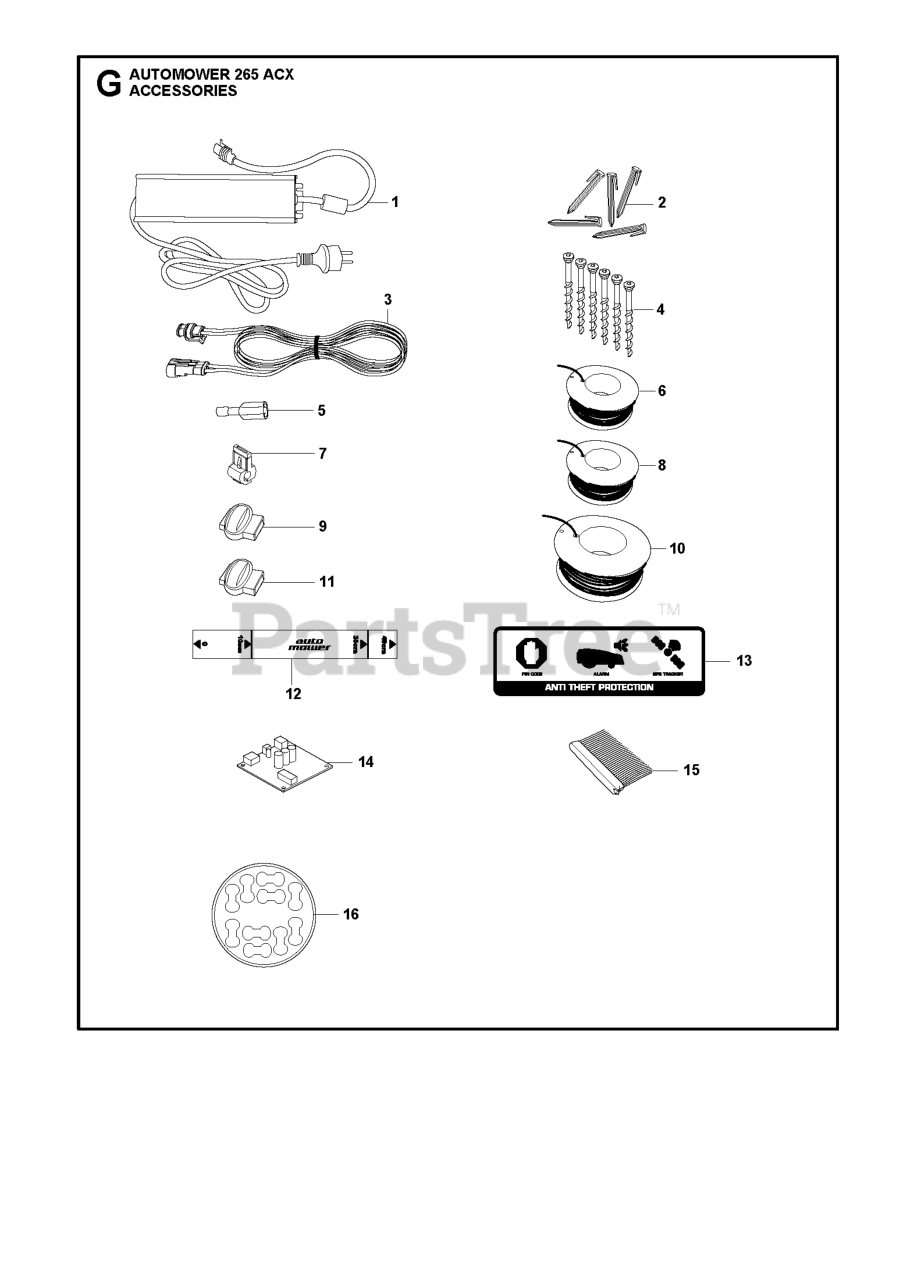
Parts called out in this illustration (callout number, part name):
2	STAPLE 100 PCS, BLISTER
4	SCREW 3 PCS, BLISTER PACK
4	Screws
6	WIRE 150M, BLISTER
7	BRAKER
7	CONNECTOR 5 PCS, BLISTER
8	WIRE 250M
9	SPLICE KIT
9	COUPLER SPLICER, 5 PCS,
10	WIRE 500M
11	COUPLER SPLICER, 100 PCS
14	CIRCUIT BOARD ASSY PCBA GEN BO
15	BRUSH KIT
16	STICKER CABLE MARKERS KIT 10PC
